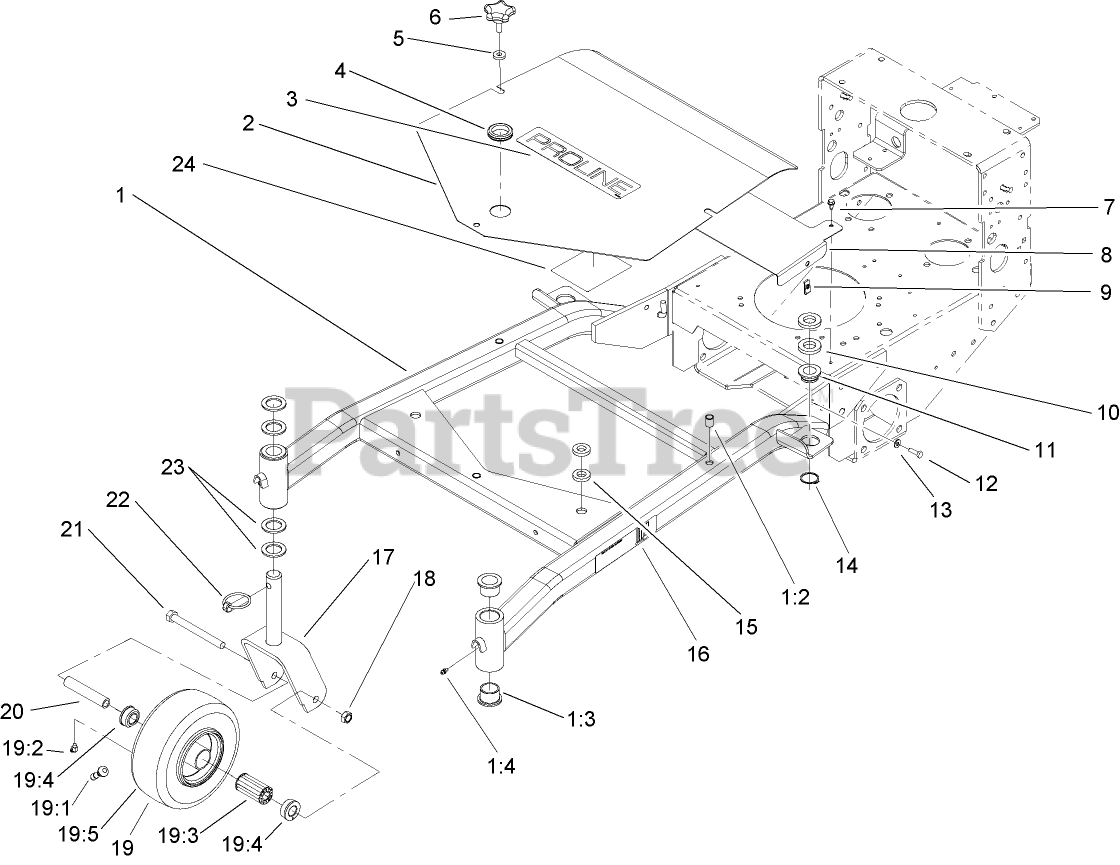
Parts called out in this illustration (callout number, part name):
1	Carrier Frame ASM
1:2	INSERT-NUT
1:3	BUSHING
1:4	FITTING-GREASE
2	Cover-Frame, Carrier
4	GROMMET-RUBBER
5	WASHER-RUBBER
7	SCREW
8	Shield-Heat
9	NUT-SPEED
10	SPACER-SUPPORT, DECK
11	BUSHING-DECK
12	SCREW-HH
13	WASHER-FLAT
14	RING-RETAINING
15	SPACER
16	DECAL-HOC
17	FORK-CASTOR
18	NUT-HEX
19	CASTER WHEEL ASM
19:1	STEM-VALVE
19:2	FITTING-LUBE, 45 DEG
19:3	BEARING
19:4	BEARING-OUTSIDE
19:5	TIRE-TUBELESS
20	BUSHING-SPANNER
21	SCREW-HH
22	PIN-LYNCH
23	WASHER-THRUST
24	DECAL-HYDRO, TBAR
24	DECAL-GEAR, TBAR
24	DECAL-GEAR, PISTOL GRIP
24	DECAL-HYDRO, PISTOL GRIP
